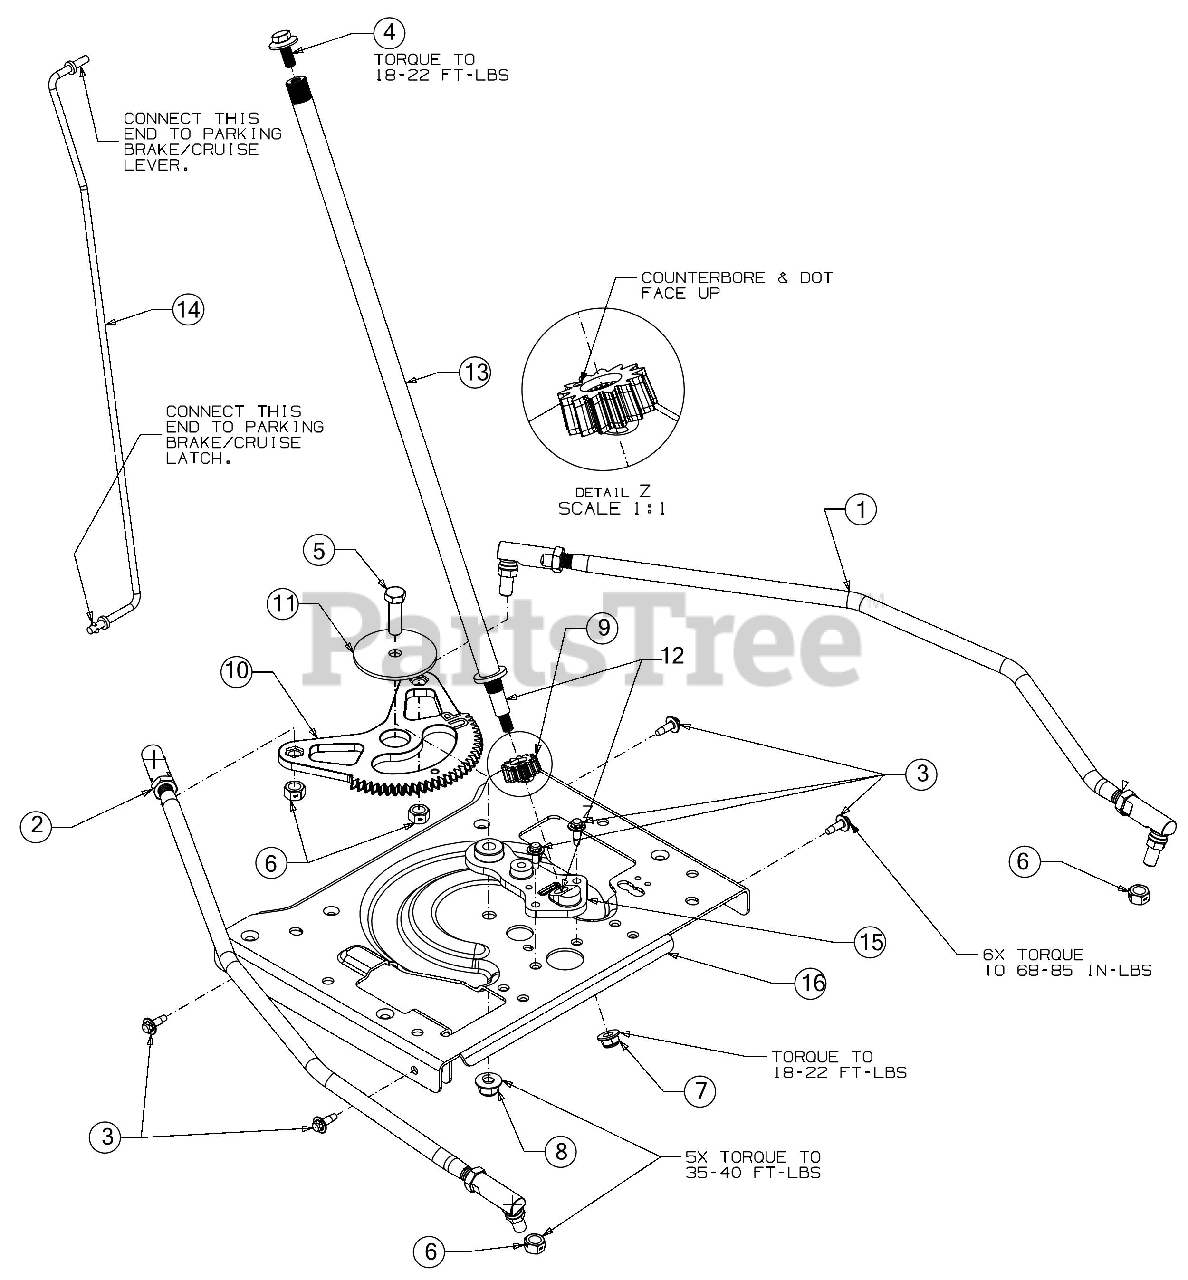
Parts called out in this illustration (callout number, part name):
1	STEERING DRAG LINK (LH)
2	STEERING DRAG LINK (RH)
3	SCREW M6-1 X .625
4	SCREW 5/16-24 X .85 GR5
5	SCREW 3/8-16 X 1.25 GR5
6	HEX NUT
7	FLANGE LOCK NUT 5/16-18
9	STEERING PINION GEAR
10	STEERING GEAR SEGMENT
11	FLAT WASHER .39 X 2.49 X .119 THK
12	GREASE-#251 EP (NOT SERVICEABLE)
13	STEERING SHAFT .625 X 20
14	CRUISE/BRAKE ROD
15	STEERING SUPPORT PLATE
16	STEERING MOUNTING PLATE
